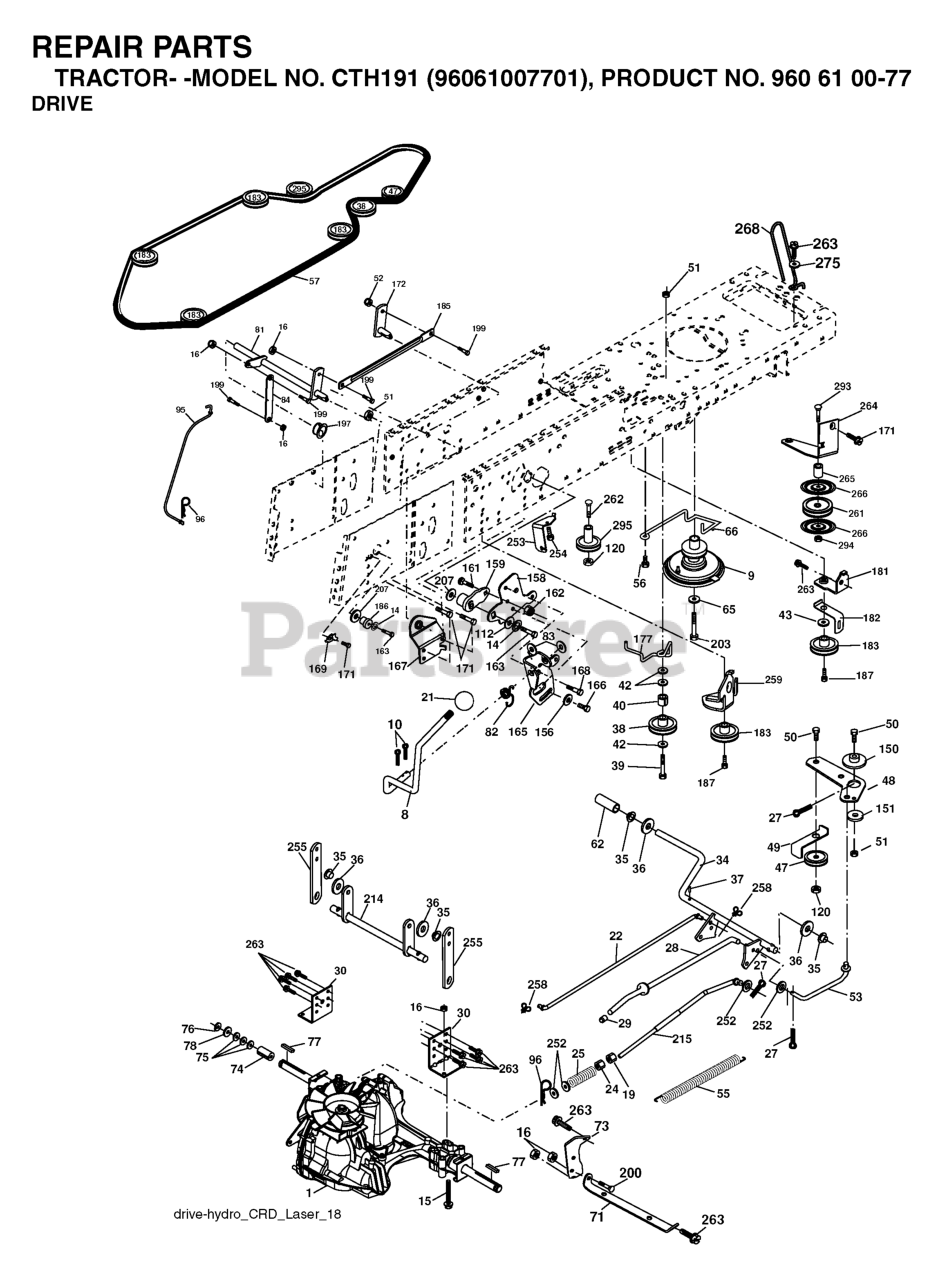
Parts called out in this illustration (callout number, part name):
8	ROD SHIFT FENDER ADJUST LT
9	RP CLUTCH.NORAM.2002
10	PIN COTTER
14	LOCKWASHER
15	BOLT HEX 5/16-18 GR 5
16	NUT.71038.31-18.HEX.NYLOCK
19	NUT
21	KNOB.DUCKHEAD.1/2
22	ROD
24	NUT
25	SPRING BRAKE ROD
27	COTTER PIN
28	ROD, PARKING BRAKE
29	PLUNGER CAP
30	BRKT, TRNSXLE MNT 20"
34	SHAFT, FOOT PEDAL
35	BEARING.NYLON
37	DRIVE PIN
38	FLAT IDLER PULLEY
42	WASHER
47	IDLER PULLEY
48	BELLCRANK, CLUTCH
49	RETAIN BELT
50	BOLT.3/8-16X1.50
52	LOCKNUT
53	LINK.CLUTCH.7.66.2005
55	SPRING, RETURN LT
56	SCREW.3/8-16
57	V-BELT 113"
62	COVER, PEDAL (1 2)
65	LOCKWASHER
66	KEEPER BELT ENGINE
71	STRAP TORQUE LH HYDRO
73	STRAP TORQUE RH HYDRO
74	SPACER AXLE
77	SQUARE KEY
81	ASM.CROSS.SHAFT.REAR.CRD.0510
82	SHIFT SPRING
83	WASHER
84	LINK.PNT.TRANSAXLE.0510.CRD
95	LINK
96	RETAINER M
120	NUT LOCK FLG 3/8-16 UNC
150	BUSHING.BELLCRANK.GRD.DR
151	WASHER 12/32X2X10GA
156	WASHER.SRRTD.5/16
158	BRACKET
159	RB HUB.SHIFT
161	BOLT
162	NUT.CROWNLOCK.1/4
165	RP BRACKET
166	CAPSCREW.HXHD.FLG.5/16-18X.625
167	BRACKET.SUPT.SHIFT.CRD
168	BOLT.SHOULDER.5/16-18X
169	PLATE.FASTENING.CROSS.SHAFT
172	LINK
181	BRACKET
182	BELT GUIDE
183	PULLEY.V-IDLER.GRND.DR
185	LINK
186	HUB.TAPERED.ROUND.CRD
187	BOLT.5/16-18X1.25
197	NYLINER SNAP 5/8" ID
199	BOLT SHOULDER 5/16-18 UNC
203	BOLT.HEX.7/16-20 X 5
207	WASHER NYL
214	LEVER
215	ROD
252	WASHER
254	SCREW 3/8-16X1
255	SHAFT
258	CLIP RETAINER
259	BRACKET
261	FLAT IDLER PULLEY
263	SCREW, 3/8-16X3/4
265	SPACER IDLER
266	PROTECTOR
268	GUARD MUFFLER
275	WASHER
293	BOLT.RDHD SQNK 3/8-16 X 3-1/2
294	NUT.HEX.3/8-16
295	PULLEY IDLER COMPOSITE
